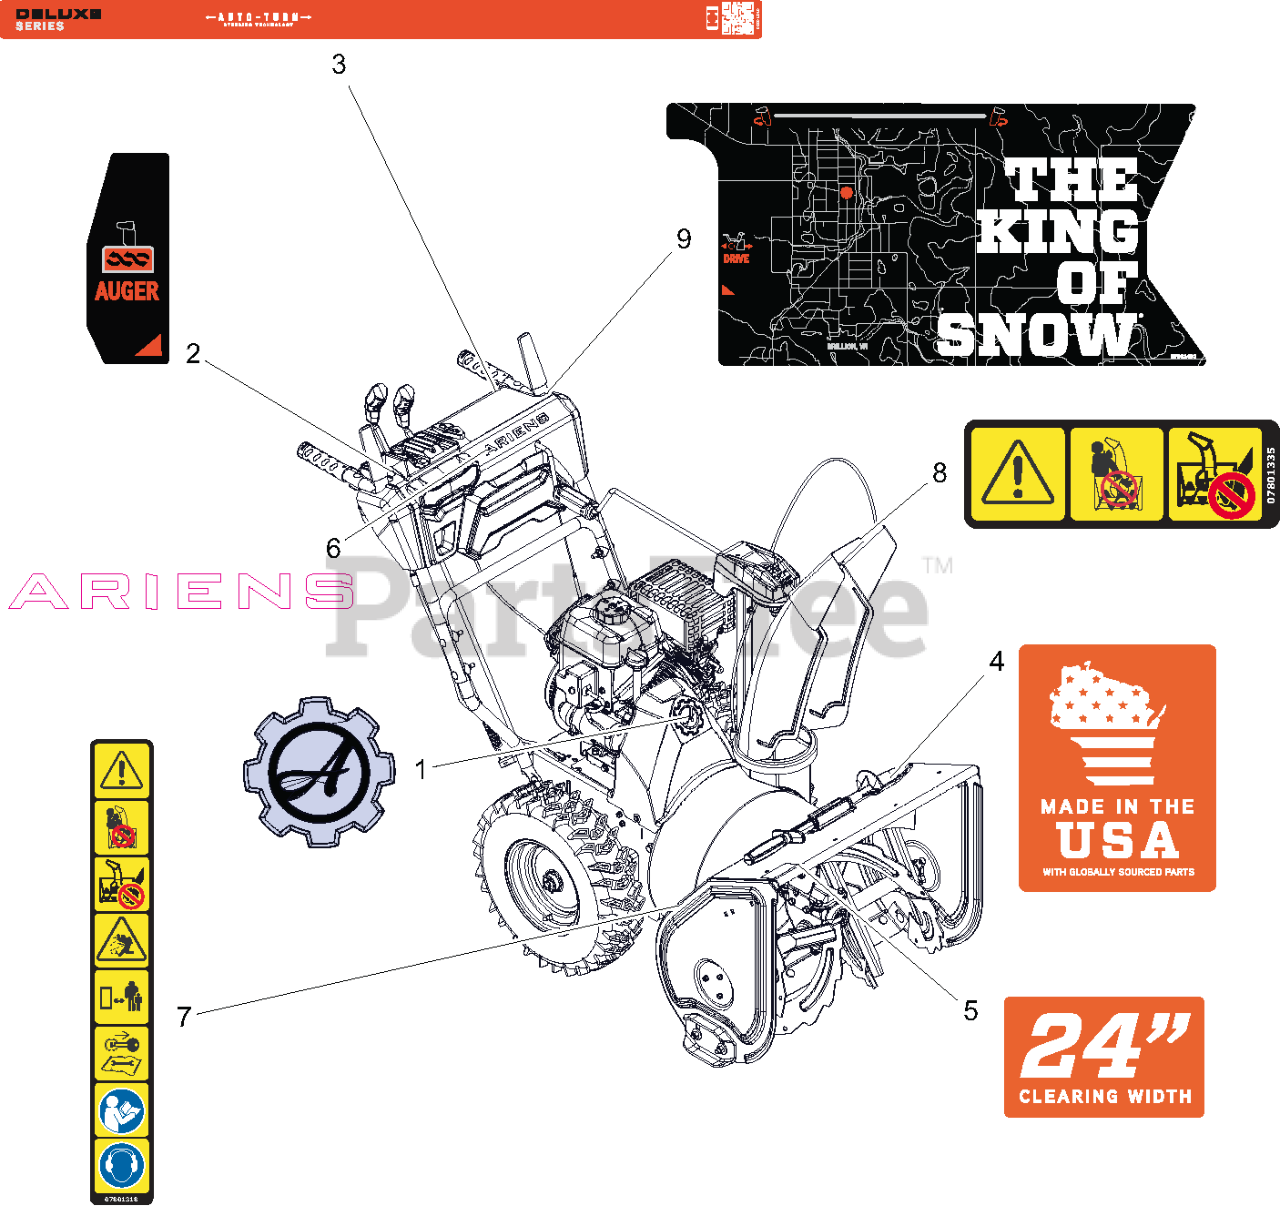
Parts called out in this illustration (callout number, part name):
1	DECAL- ARIENS GEAR BADGE
2	DECAL- CONTROL - AUGER
3	DECAL- DASH - DLX
4	DECAL- MADE IN USA
5	DECAL- CLEARING - 24
6	DECAL- ARIENS - 7.46"
7	DECAL- SAFETY - DANGER
8	DECAL- DANGER
9	DECAL-CONTROL-LG CHUTE ROTATE
